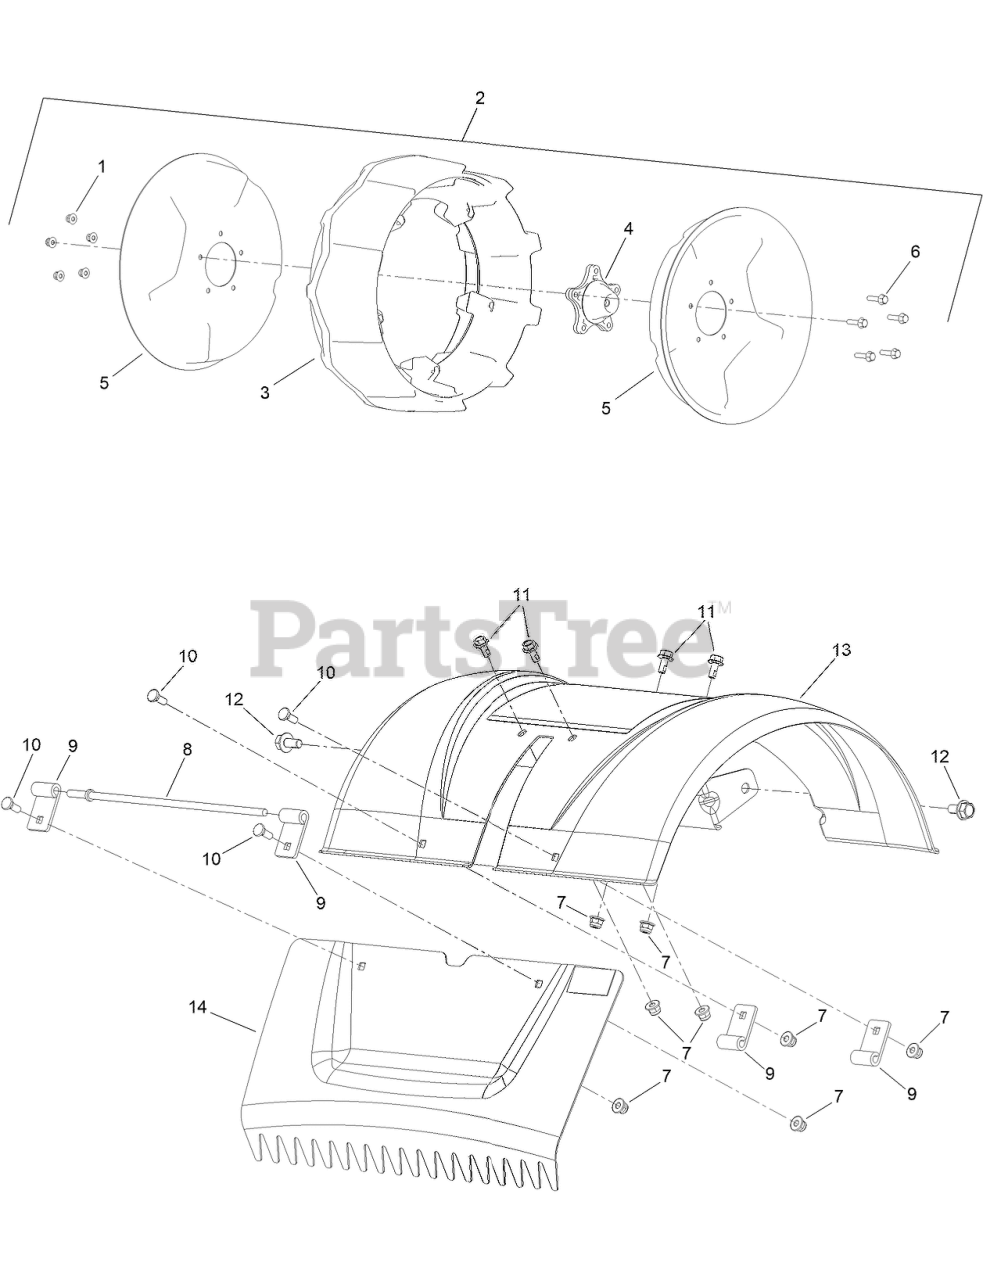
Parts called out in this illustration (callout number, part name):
1	NUT-HEX
5	RIM-HALF
6	SCREW-HHF
7	NUT-HEX
8	ROD-HINGE
9	BRACKET-HINGE
10	SCREW-CRG
11	SCREW-HF
12	SCREW-HF
13	BEAVER TAIL
14	SHIELD-TINE
